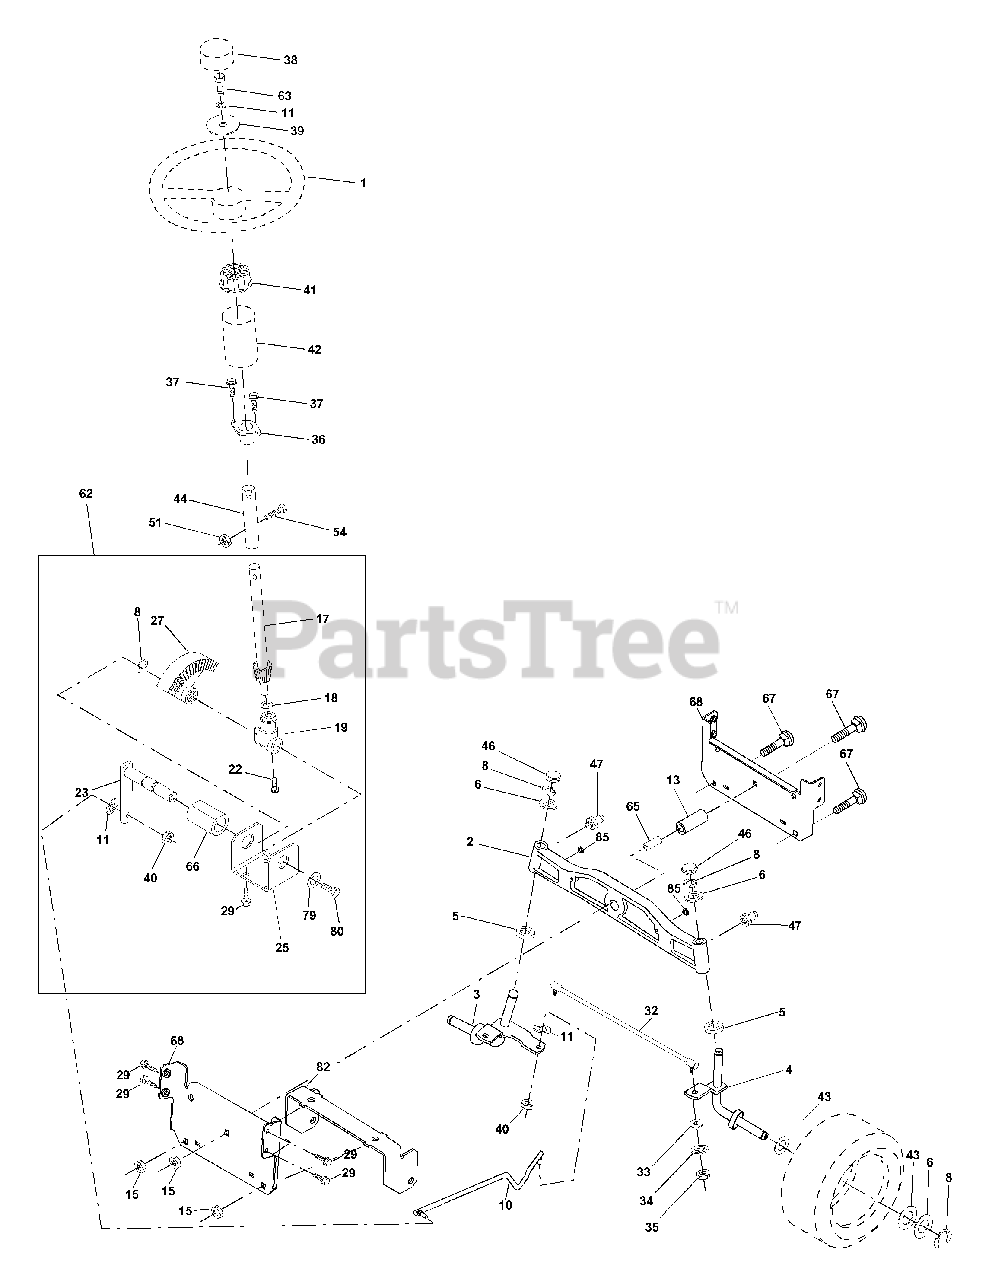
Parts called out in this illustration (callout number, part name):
1	Wheel Steering
2	Axle Asm Cast Iron LT
3	Spindle Asm LH
4	Spindle Asm RH
5	Bearing Race Thrust Harden
6	Washer 25/32 X 1-5/8 X 16 Ga
8	Ring Klip #t5304-75
10	Link Drag
11	Washer Lock Hvy Hlcl Spr 3/8
13	Spacer Brg Axle Front
15	Nut Hex Flange Lock
17	Shaft Asm Strg
18	Washer Thrust 515x 750x 033
19	Support Shaft
22	Screw Hex Wsh Hd Torx
23	Shaft Asm Pittman
25	Bracket Steering
27	Gear Sector
29	Screw 3/8-16 x .75
32	Rod Tie
33	Washer 11/32 x 3/4 x 16 Ga
34	Washer Lock Hvy Hlcl Spr 5/16
35	Crownlock Nut 5/16-24 Unf
36	Bushing Strg
37	Screw
38	Insert Cap Strg Wh
39	Washer 13/32 X 1-1/2 X 11 Ga
40	Lock nut
41	Adaptor Wheel Strg
42	Boot Steering Dash
43	Washer 25/32 X 1 1/4 X 16 Ga
44	Extension Steering Shaft LR/LT
46	Cap Spindle Fr Top Blk
47	Fitting Grease
51	Nut Lock Hex w/Ins 5/16-18
54	Bolt Fin Hex 5/16-18 Unc x 1-1/4
62	Kit, Steering Assembly Svc
63	Bolt Fin Hex 3/8-16unc x 1 Gr. 5
65	Spacer Brace Axle
66	Bearing Arm Pittman
67	Bolt Rdhd Sq 3/8-16 Unc x 2-3/4
68	Axle, Brace
79	Washer 13/32 x 1-1/4 x 12 Ga.
80	Bolt Hex Nylon 3/8-16 x 3/4
82	Bracket Susp Chassis Front
85	Fastner Christmas Tree
